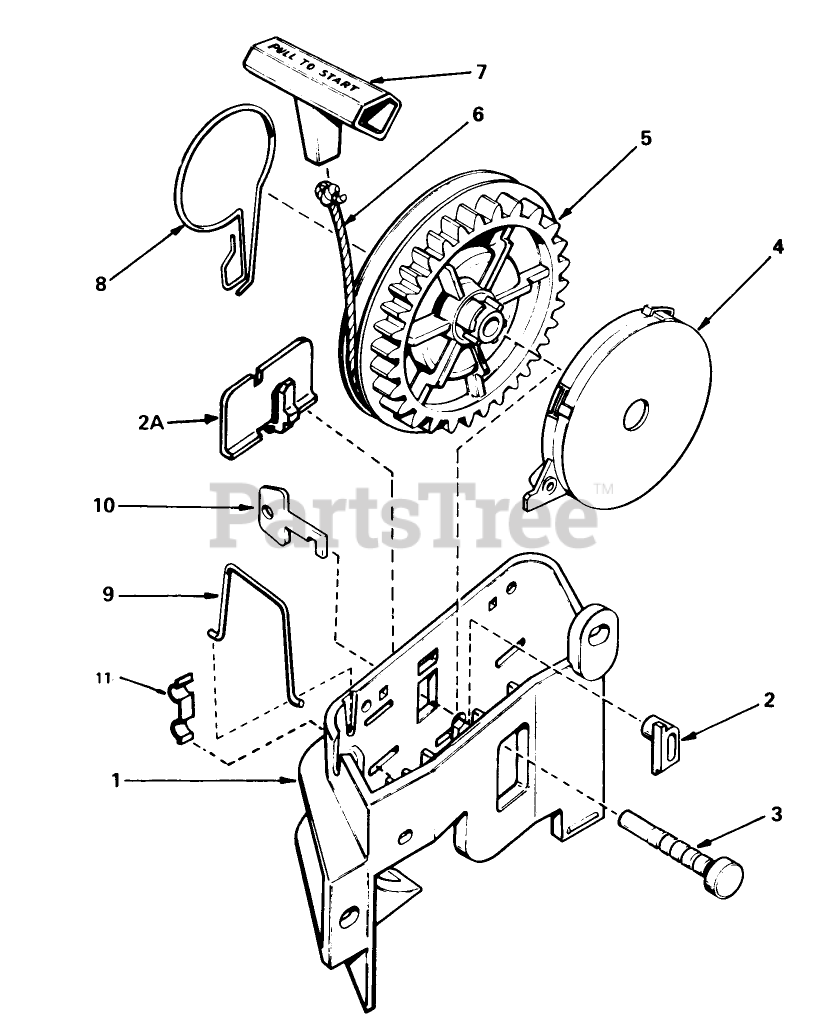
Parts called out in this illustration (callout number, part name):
1	Bracket Starter
2	Pawl, Locking Not used on all engine models)
2A	Clip, Starter Bracket (Used On Starters Not Equipped With Pawl, Ref. No. 2)
3	Pin-Pulley
4	Spring Assy., Rewind (Incl. Ref. #3)
5	Pulley
6	Rope Starter (Length 65" 9/64" Dia.)
7	Handle-Starter
8	Brake
9	Clip-Rope
10	Key (Not Used On All Engine Models
11	Washer-Thrust
